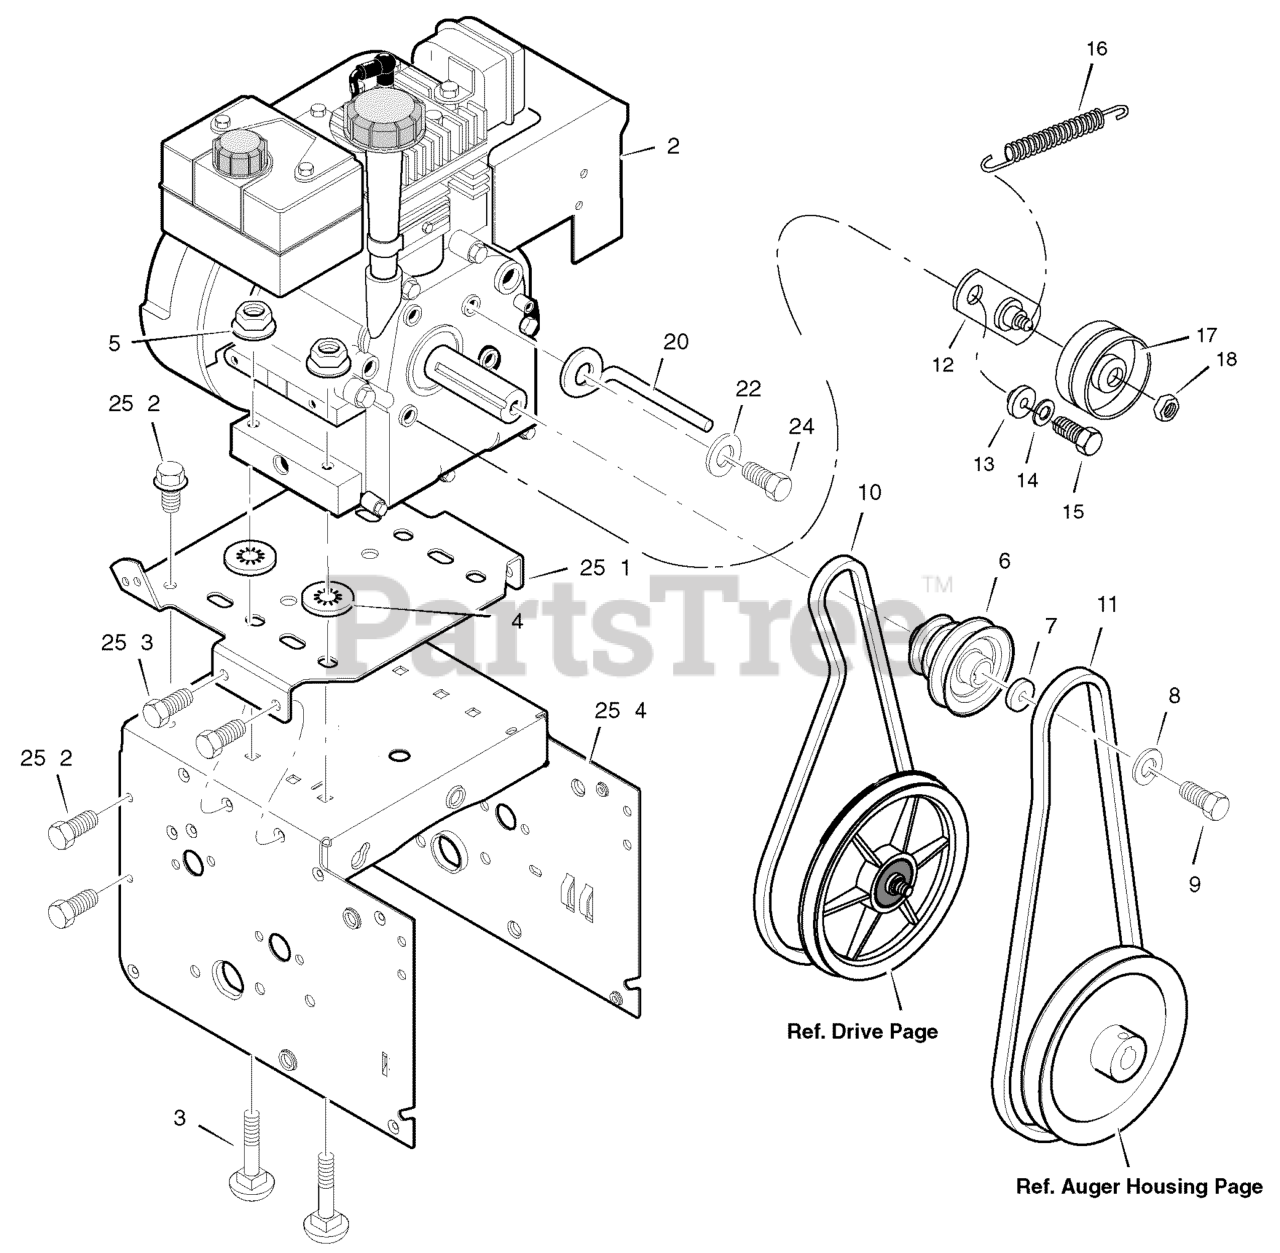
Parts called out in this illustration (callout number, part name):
2	ENGINE *
3	BOLT, CARRIAGE 5/16-18
4	RETAINER, PUSH
5	NUT 5/16-18
6	PULLEY, ENGINE
7	WASHER
8	WASHER .38ID
9	SCREW, 3/8-24 x 1.00
10	BELT, DRIVE
11	BELT, AUGER
12	BRACKET ASSEMBLY, IDLER
13	BUSHING, IDLER BRACKET
14	WASHER, SPLIT
15	SCREW 5/16-24 X 0.75
16	SPRING, IDLER TRACTION DRIVE
17	PULLEY, IDLER
18	NUT, JAM 3/8-16
20	GUIDE, BELT
22	WASHER .31X.58X.08
24	SCREW, 5/16-24 x 0.75
